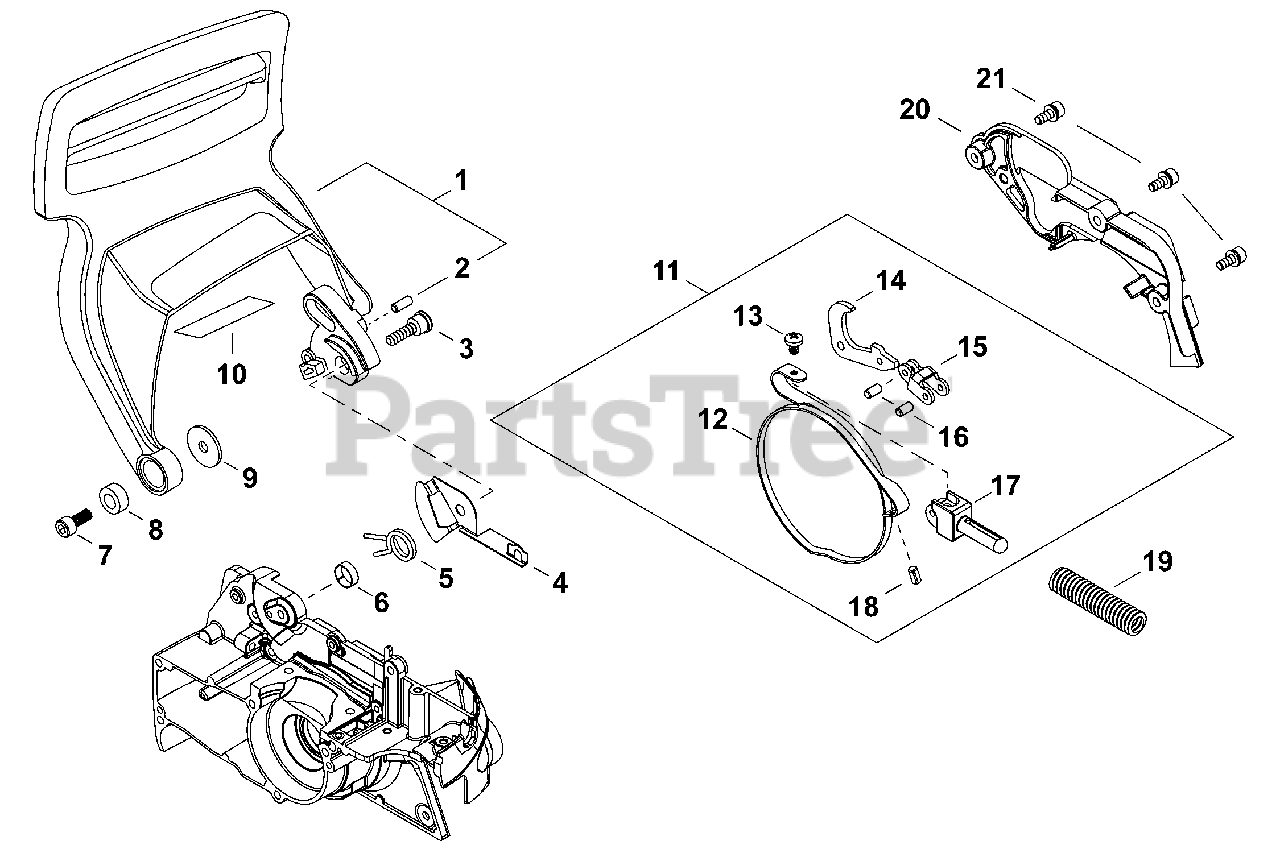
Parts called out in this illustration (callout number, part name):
1	LEVER ASSY, BRAKE
2	PIN, LOCATING Ø4×8
3	BOLT, ADHESIVE M4×38
4	PLATE, RETAINING
5	SPRING, TORSION
6	COLLAR 8
7	BOLT, ADHESIVE 5
9	WASHER 5
10	SHIELD, HEAT 35×60×0.10
11	BRAKE ASSY, BAND
12	BAND, BRAKE
13	SCREW, TAPPING M4×10
14	LEVER, BRAKE
15	STRAP, TIE
16	PIN 3×12
17	CONNECTOR, BRAKE
18	PIN, SPRING Ø4×10mm
19	SPRING, BRAKE
20	COVER, BRAKE
21	BOLT, ADHESIVE M4×10
